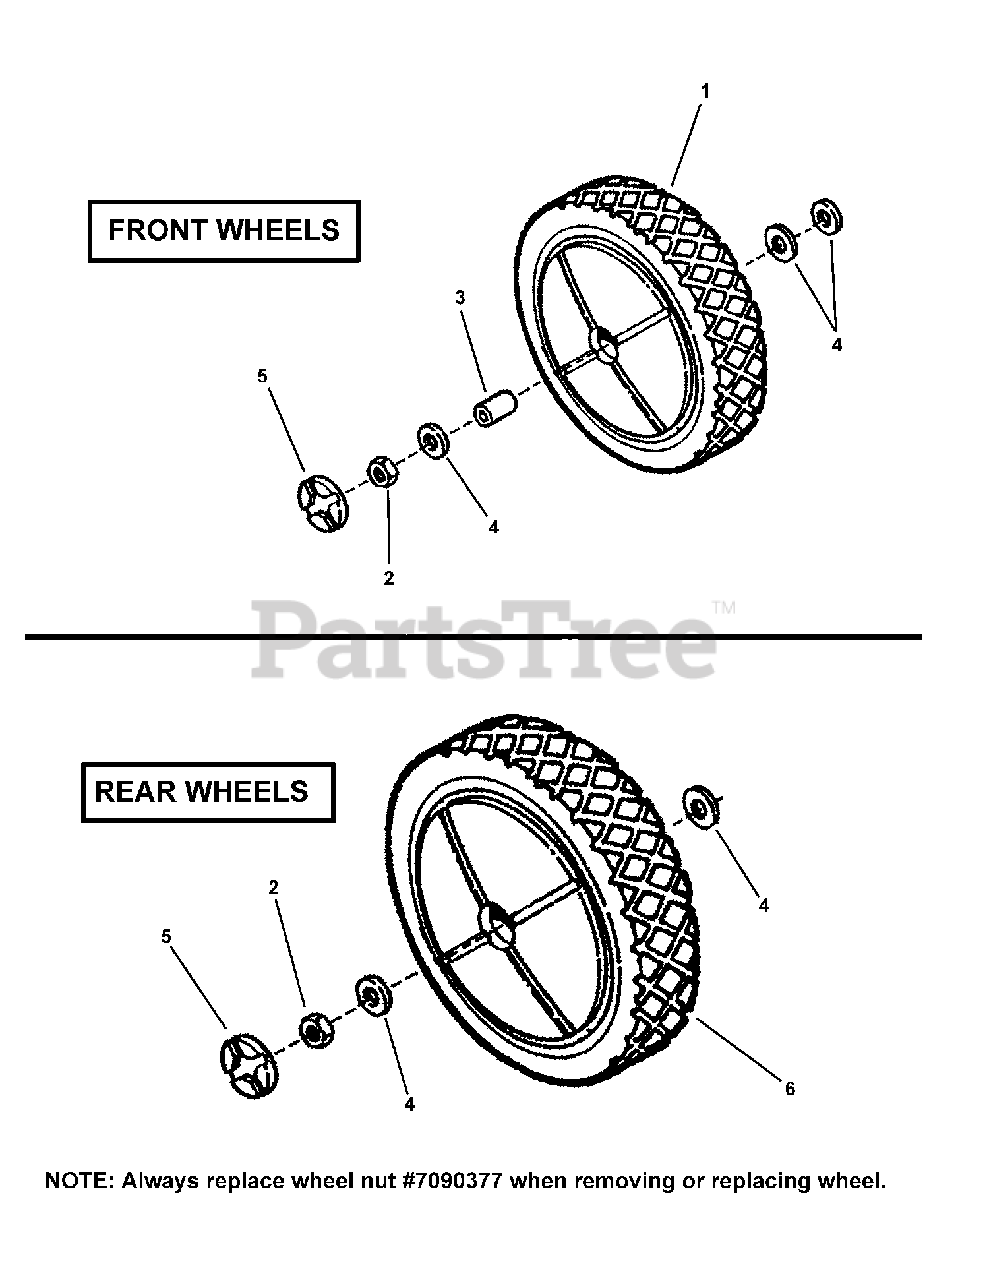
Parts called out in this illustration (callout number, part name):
1	WHEEL, 8 x 1.75" Plastic
2	NUT, 7/16-20 Hex Center Lock Jam
3	BUSHING, Axle
4	WASHER, 7/16" Flat
5	PLUG, Wheel
6	WHEEL, 10 x 1.75" Plastic
6	WHEEL ASSY, 10 x 1.75
